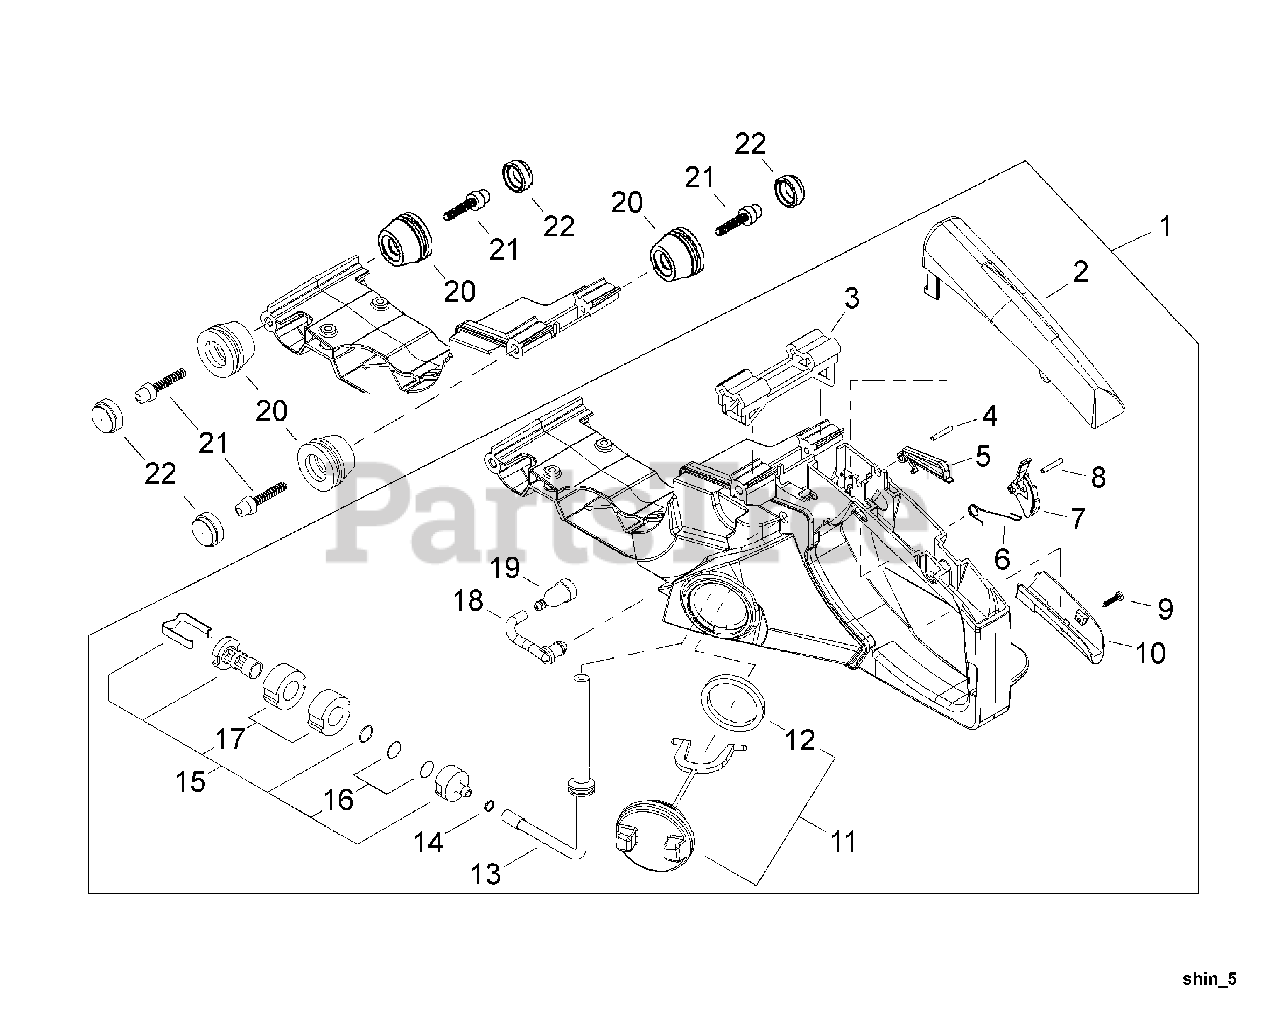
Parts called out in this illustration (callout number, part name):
1	HANDLE ASSY - REAR
2	GRIP - UPPER
3	CUSHION
4	PIN
5	LEVER, TRIGGER LOCKOUT
6	SPRING, LEVER
7	TRIGGER, THROTTLE
8	PIN - 4X25
9	SCREW - 4X22 -- TAPPING
10	GRIP - LOWER
11	CAP ASSY
12	GASKET, CAP
13	PIPE - FUEL
14	RING, RETAINING - 6
15	FILTER, FUEL
16	SCREEN, FILTER
17	FILTER, FUEL
18	PIPE - VENT
19	ELEMENT, BREATHER
20	CUSHION
21	BOLT
22	PLUG
